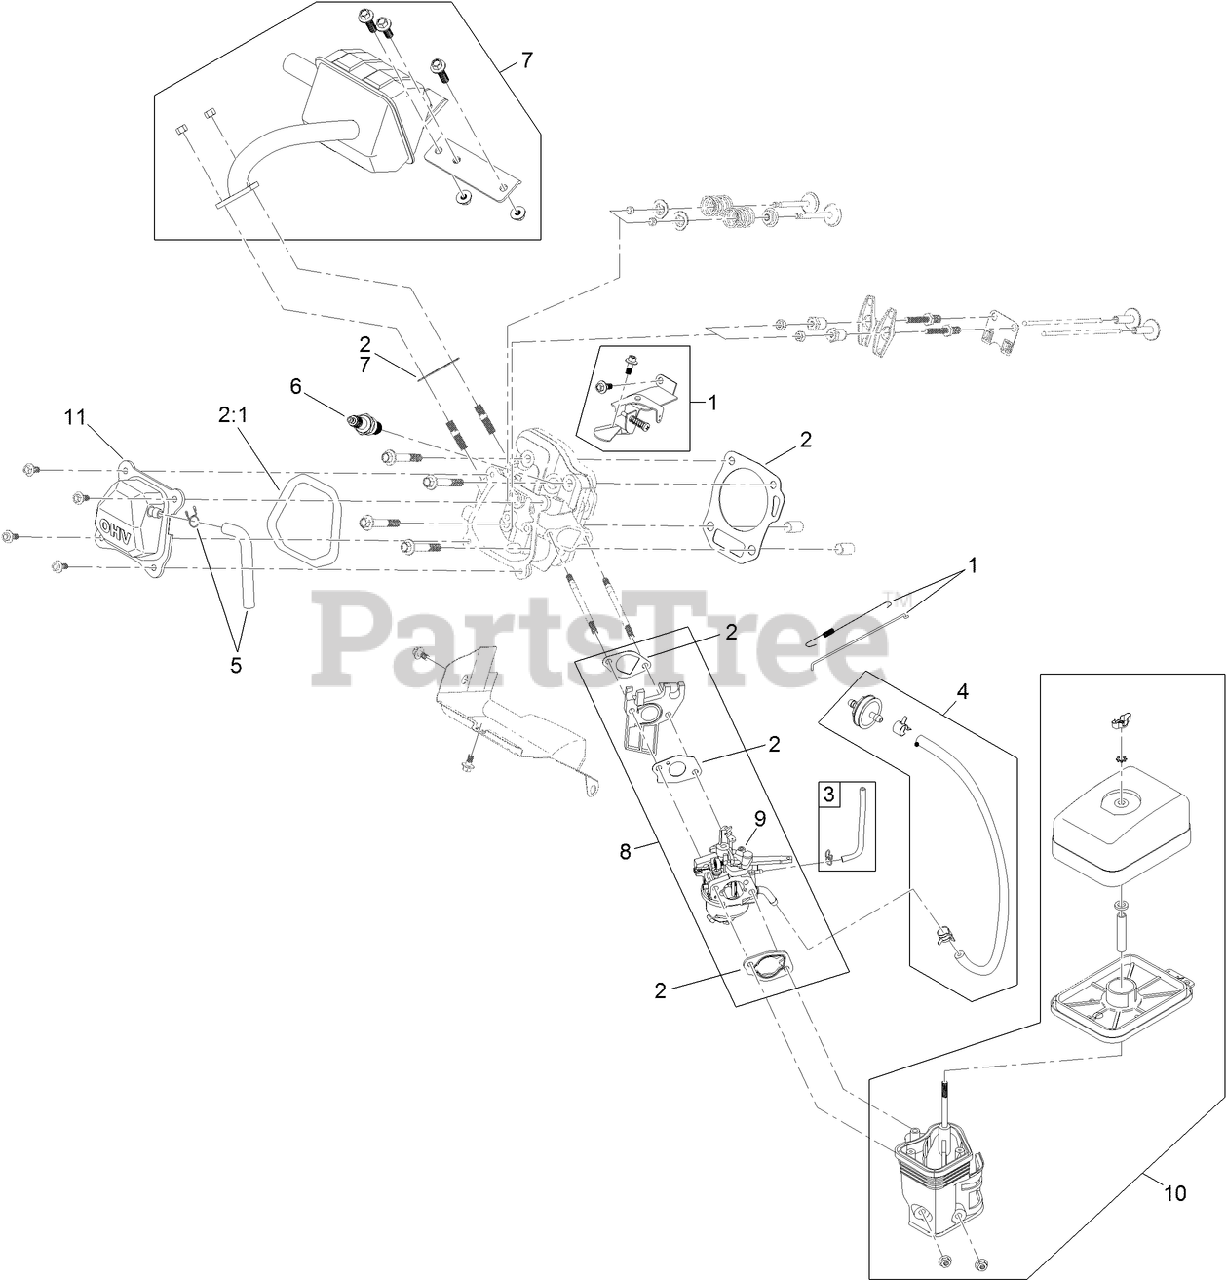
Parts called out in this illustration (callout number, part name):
1	GOVERNOR KIT
2	GASKET AND SEAL KIT
2:1	GASKET-COVER, VALVE
4	FUEL LINE KIT
5	BREATHER TUBE KIT
7	MUFFLER KIT
8	COMPLETE CARBURETOR SERVICE KIT
10	HEATER BOX KIT
11	VALVE COVER ASM
